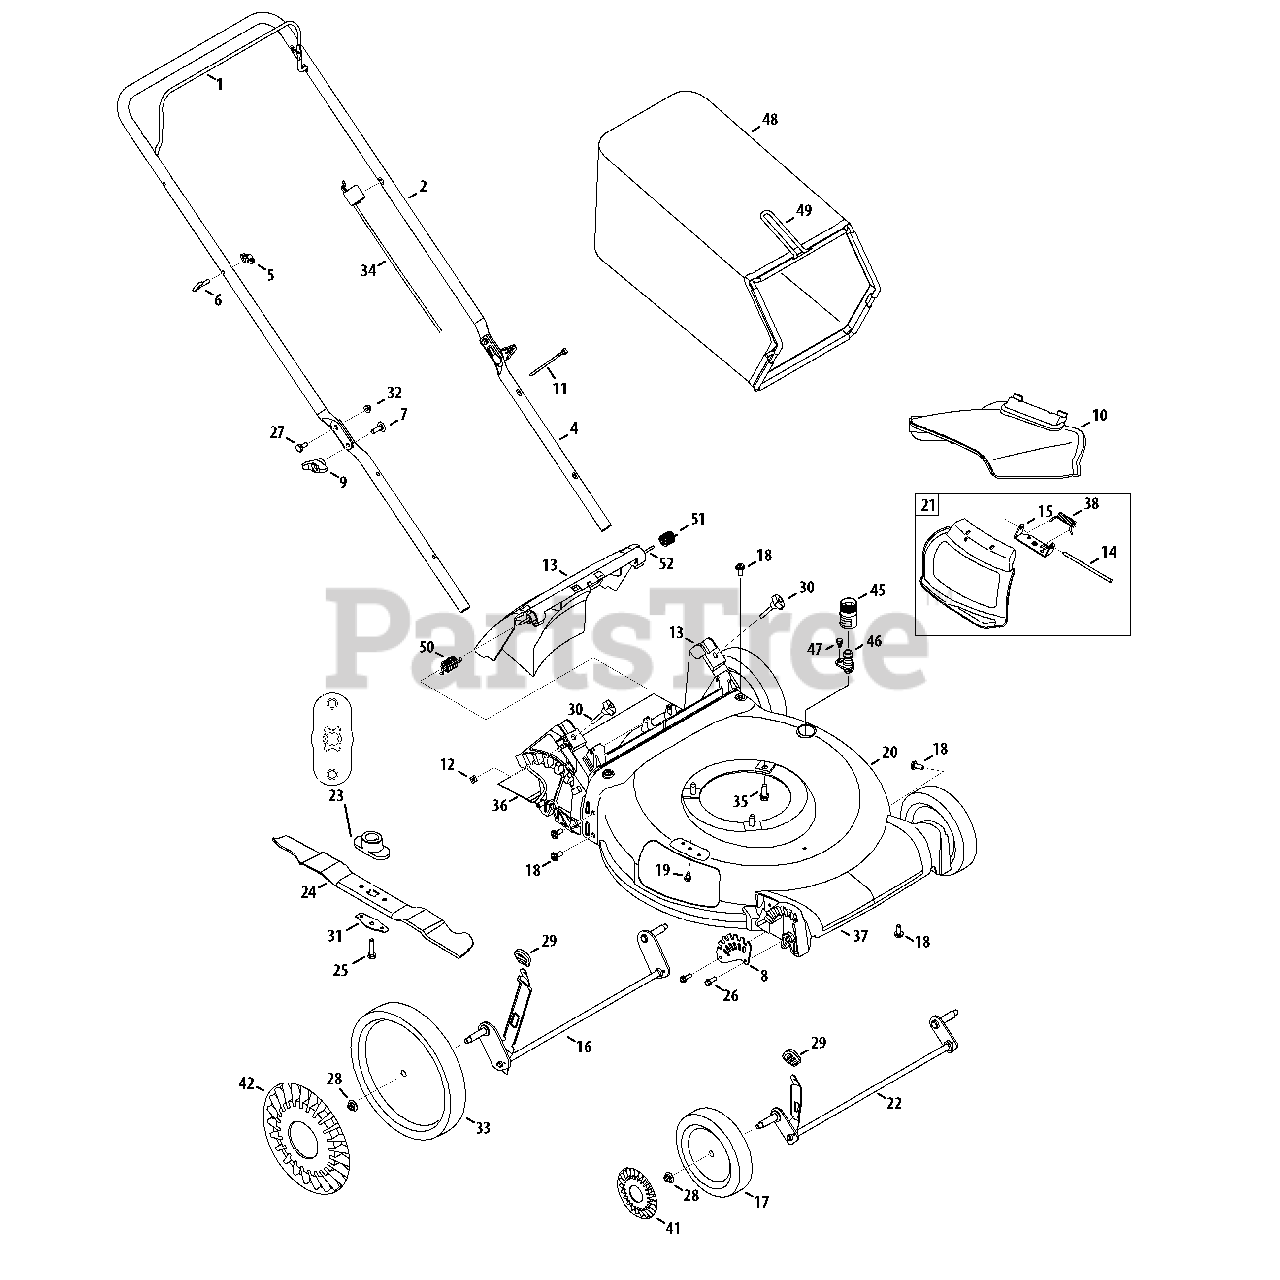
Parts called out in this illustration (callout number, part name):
1	Blade Control Handle - Black
2	Upper Handle - Black (adjustable)
4	Lower Handle
5	Knob 1/4-20
6	Rope Guide Bolt
7	Carriage Bolt 5/16-18
8	Front Height Adjustment Plate
9	Wing Knob 5/16-18 Black
10	Chute Deflector (w/clip)
11	Cable Tie
12	Sq. Nut 1/4-20
13	Rear Baffle
14	Hinge Pin
15	Chute Deflector Bracket
16	Rear Axle Ass’y - 8" wheel
17	Wheel Ass’y 7 x 2.0 Sleeve Zag Black
18	Hex Hd. Cap Scr. 5/16-14 x .75
19	Sems TT Scr. 1/4-20 x .50
20	21" Deck Ass’y (3 in 1 w/washout nozzle)
21	Hinged Mulch Plug Ass’y
22	Front Axle Ass’y - 7 " wheel
23	Blade Adapter (25 mm x 1.19)
24	21" Mulching Blade
25	Hex Bolt 3/8-24 x 1.5" Lg. (Gr 8)
26	Screw, 1/4-15 x .750
27	Shoulder Screw .375 x .126 x 1/4-20
28	Flange Locknut 3/8-16 Gr. F Nylon
29	Knob (Black)
30	Knob 1/4-20 x 1.725 Black
31	Blade Bell Support
32	Flanged Lock Nut 1/4-20 Gr. F Nylon
33	Wheel Ass’y 11 x 2 SL: Zag Black
34	Control Cable, 160 cc Honda
35	Hex Wash HD Tap Scr 3/8-16 x 1.0
36	Trailing Shield 4.54 x 17.37
37	Front Axle Cover
38	Torsion Spring
41	Hub Cap (8")
42	Hub Cap (11")
45	Water Nozzle Adapter
46	Deck Water Nozzle
47	Shoulder Screw 1/4-20 x .50
48	Grassbag, Black Dust Blocking
50	Torsion Spring RH
51	Torsion Spring LH
52	Pivot Rod
